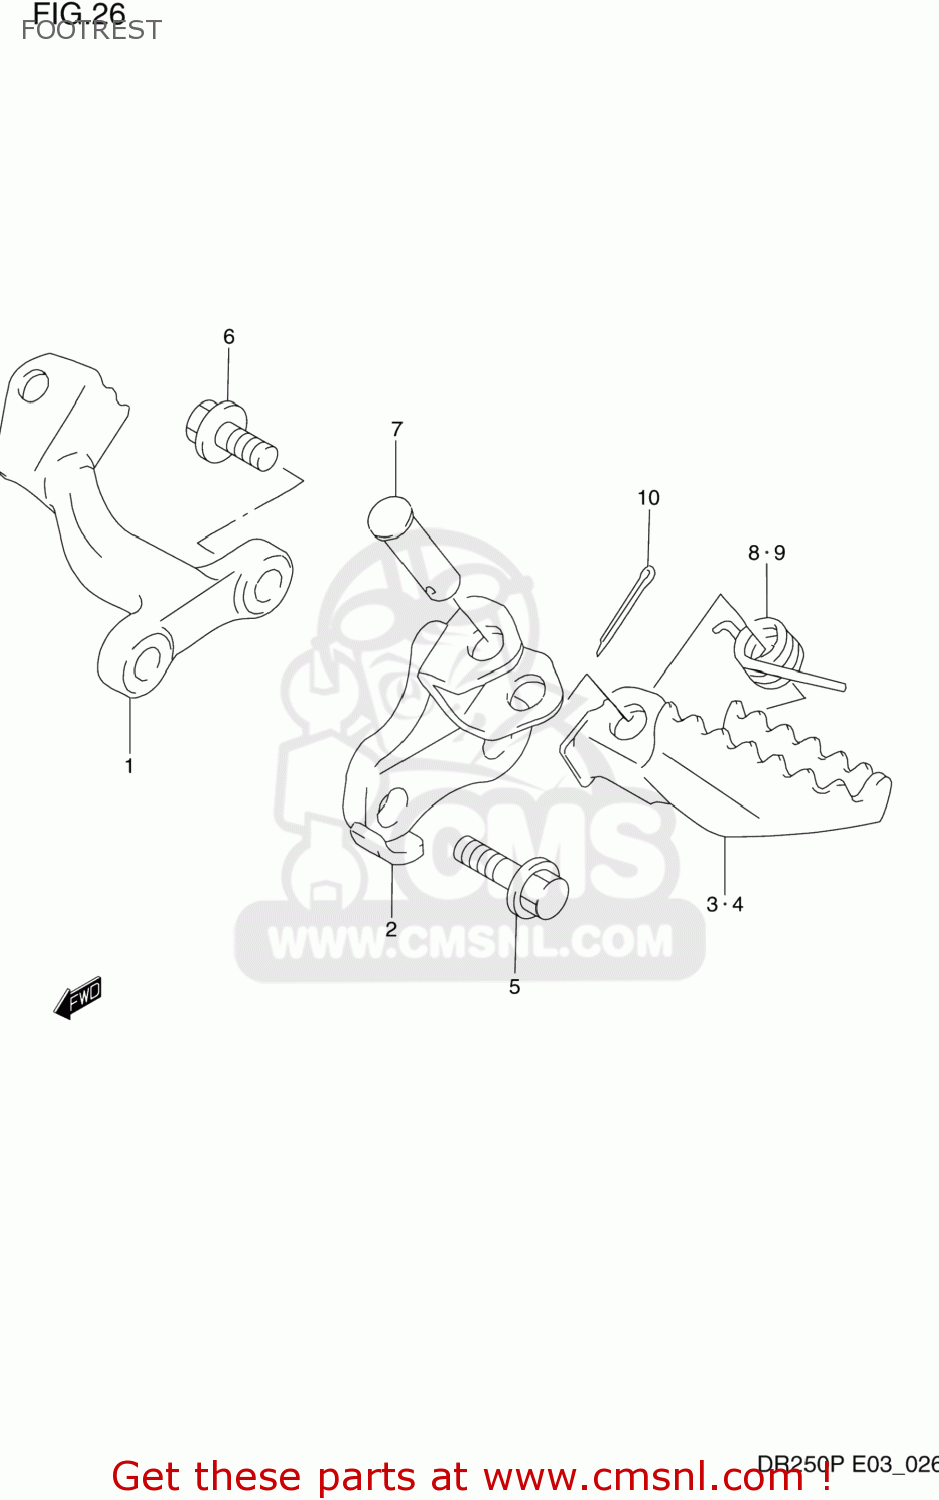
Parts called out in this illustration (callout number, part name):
1	BRACKET,FRONT FOOTREST
2	BRACKET COMP,FRONT FOOTREST
3	FOOTREST COMP,FRONT,RIGHT
4	FOOTREST
5	BOLT
6	BOLT
7	PIN
8	SPRING
9	SPRING
10	PIN 20X20
